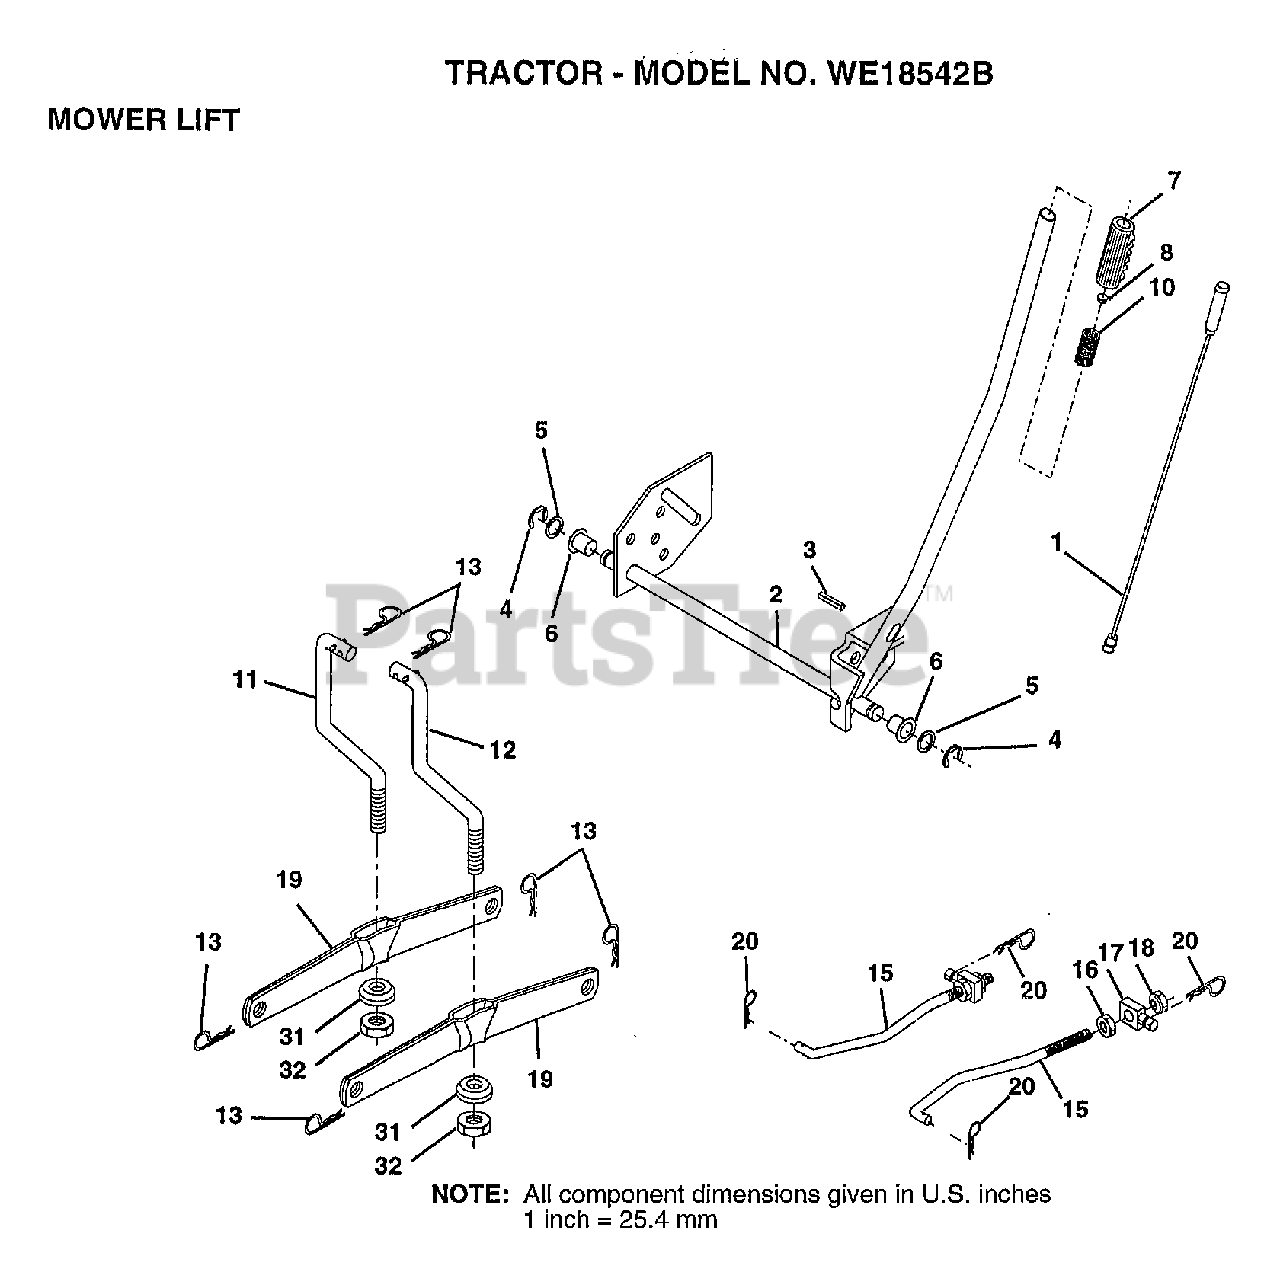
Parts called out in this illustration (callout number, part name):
1	WIRE ASM W.SPRING
2	"SHAFT ASM LIFT,RH"
3	PIN-GROOVE LT
5	WASHER
6	NYLON BEARING
7	GRIP
15	LINK.FRONT
16	NUT
17	TRUNION
18	NUT.LK.W/WSH.1/2.
19	ARM SUSP REAR
20	RETAINER.SPRING
31	BEARING PVT LH
32	NUT.CROWNLOCK.3/8
